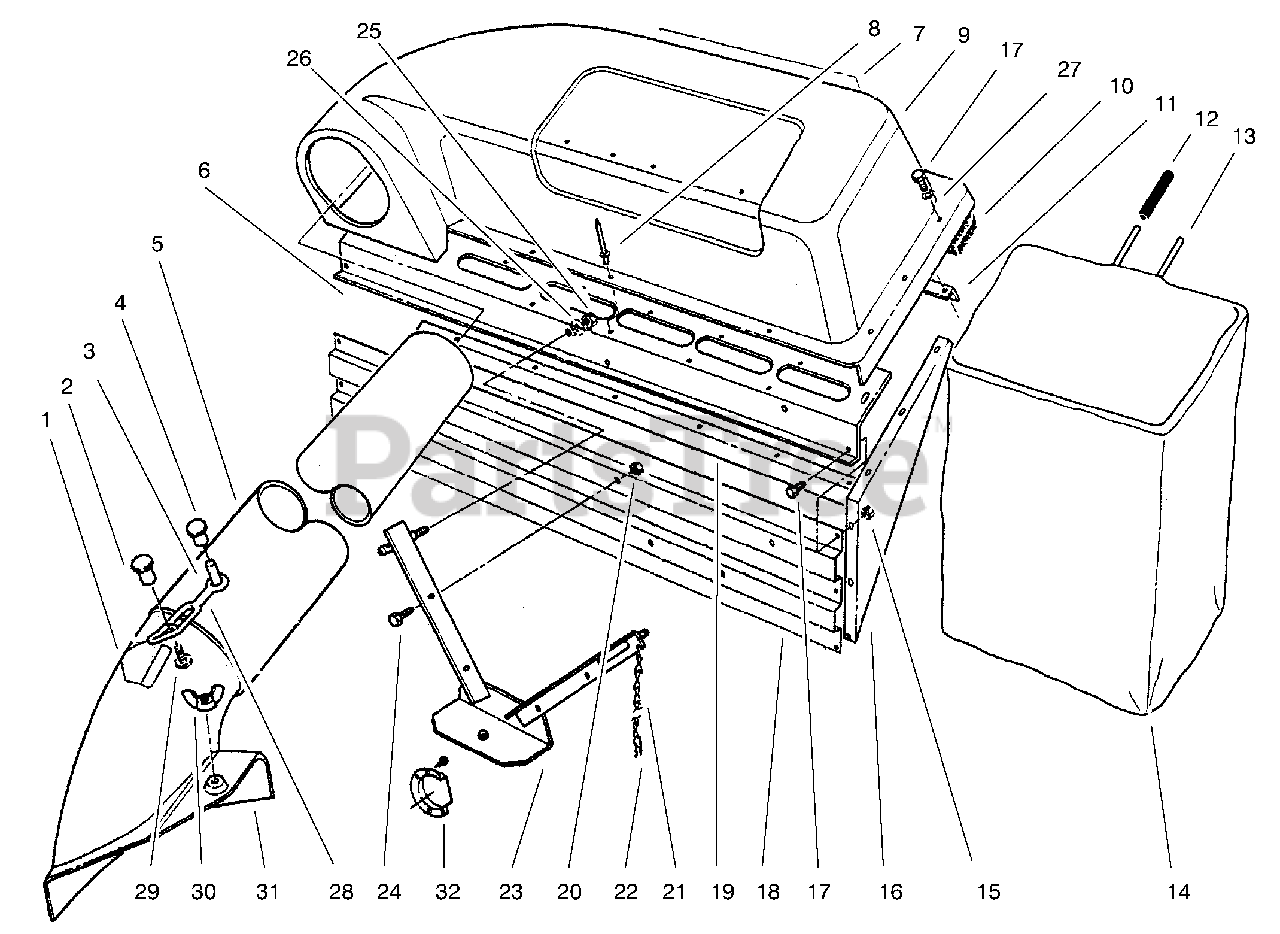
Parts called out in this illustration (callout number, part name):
1	Decal
3	SPACER-INTERLOCK
4	FASTENER-PANEL
5	Duct
7	Decal-Twin Bagger
10	FOAM SEAL
11	BAG FRAME BRKT
12	GRIP-HANDLE, BAG
13	BAG FRAME
15	NUT-LOCK, NI
16	SIDE PLATE (BLACK)
17	SCREW-HH
18	Shield-Muffler
19	BAG SUPPORT CHANNEL
20	NUT-LOCK, NI
21	6-LINK CHAIN W/HOOK
23	V BRACKET WA (BLACK)
24	SCREW-HH
25	Locknut
26	WASHER-FLAT
27	WASHER-FLAT
28	RETAINER-DUCT
29	SCREW-HWHTF
30	NUT-WING SPECL
31	Assembly-Chute (Incl. Ref. #1, 2 & 29)
32	MUFFLER DEFLECTOR
